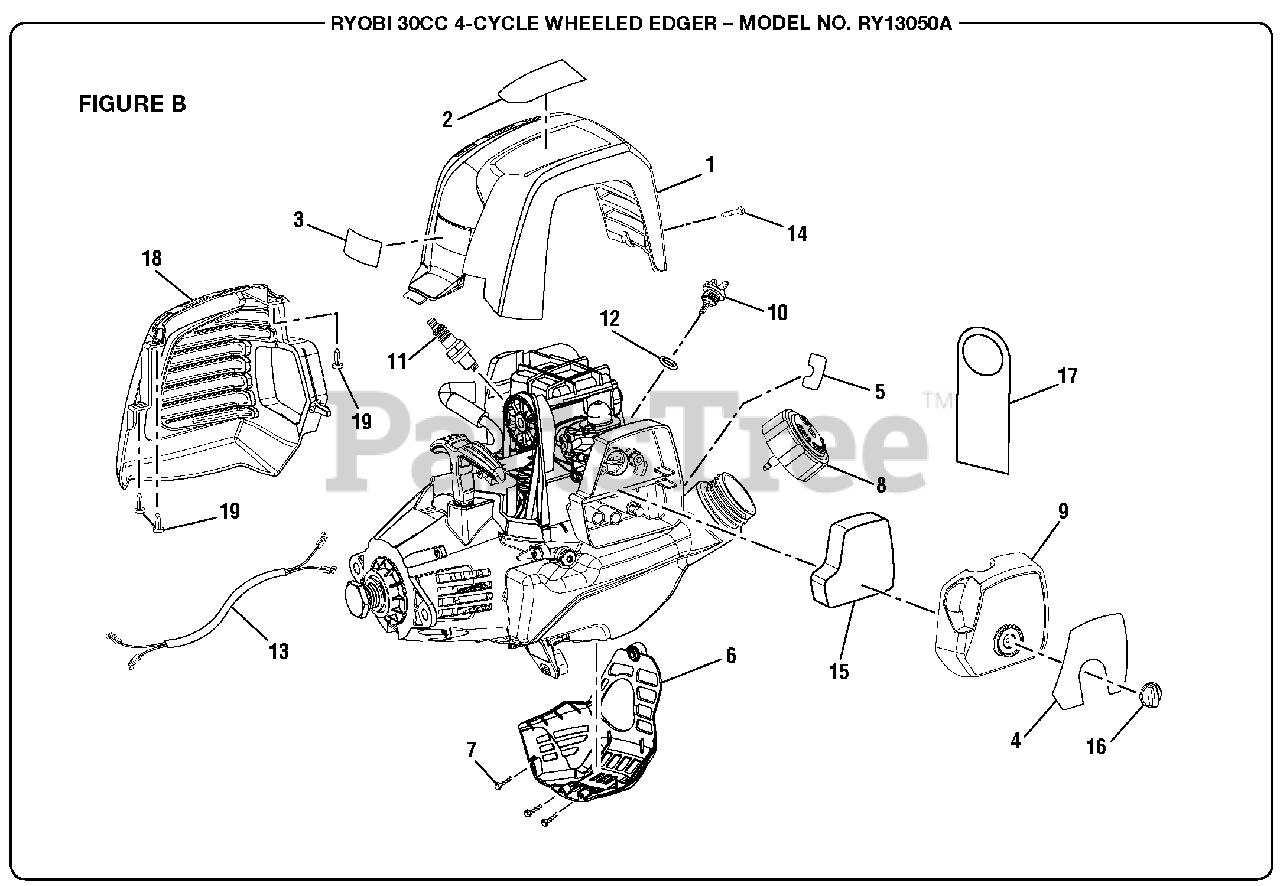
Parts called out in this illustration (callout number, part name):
1	Top Cover
2	Label
3	Logo Label
4	Starting Label
5	Hot Surface Label
6	Bottom Cover
7	Screw (M6-19 x 1/2 in.)
8	Fuel Cap Assembly
9	Air Box Cover (Incl. key no. 16)
10	Oil Cap/Dipstick (Incl. key no. 12)
11	Spark Plug (Champion RZ7C)
13	Wiring Harness
14	Screw (M4 x 20 mm)
15	Air Filter
16	Air Cover Knob
18	Muffler Cover
19	Screw (M4 x 12 mm)
